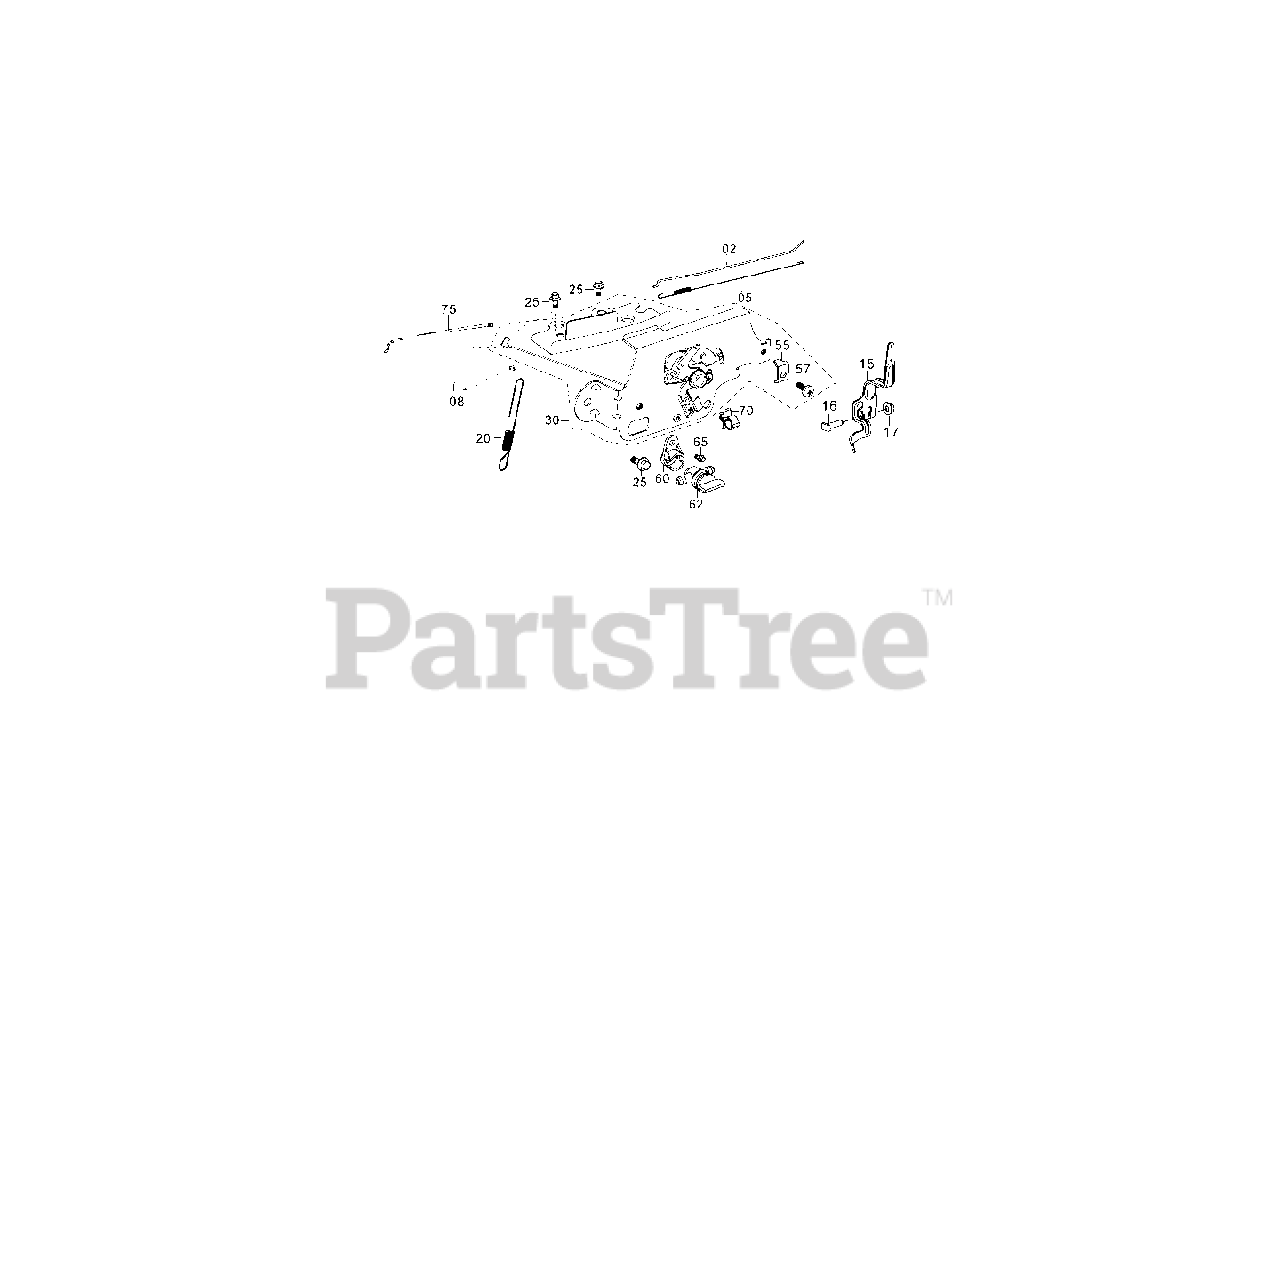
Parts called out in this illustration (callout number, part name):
400-02	THROTTLE CONTROL ROD
400-05	THROTTLE RETURNING SPRING
400-20	GOVERNOR SPRING
400-30	SPEED CONTROL BRACKET ASSY
400-60	FUEL VALVE BASE
400-70	PLASTIC CLAMP
